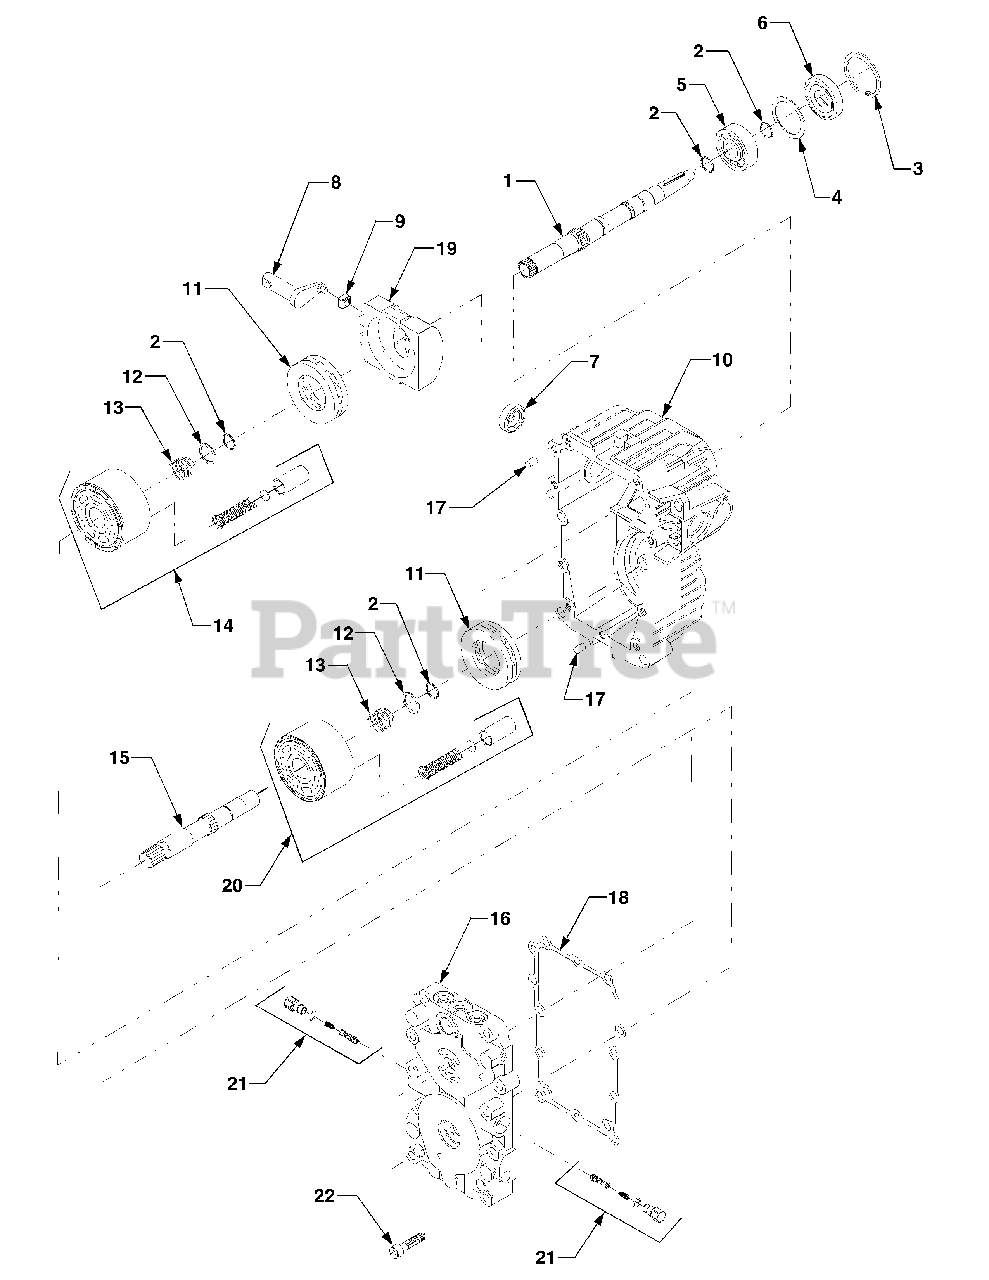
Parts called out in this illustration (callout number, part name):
1	Shaft, Pump Input 1B065G & Before
1	Shaft, Pump Input 1B075G & After
2	Ring, Wire Retaining
3	Ring, Retaining
5	Bearing, Ball
6	Seal, Lip
8	Arm, Trunnion
9	Guide, Slot
10	Housing Assembly
11	Bearing Assembly, Thrust Ball
12	Washer, Block Thrust
13	Spring, Block
14	Kit, Pump Cylinder Block
15	Shaft, Motor
16	Kit, Center Section
18	Gasket, Center Section
19	Swashplate, Variable
20	Kit, Motor Cylinder Block
21	Shock Valve
22	Screw, Socket Head Cap
